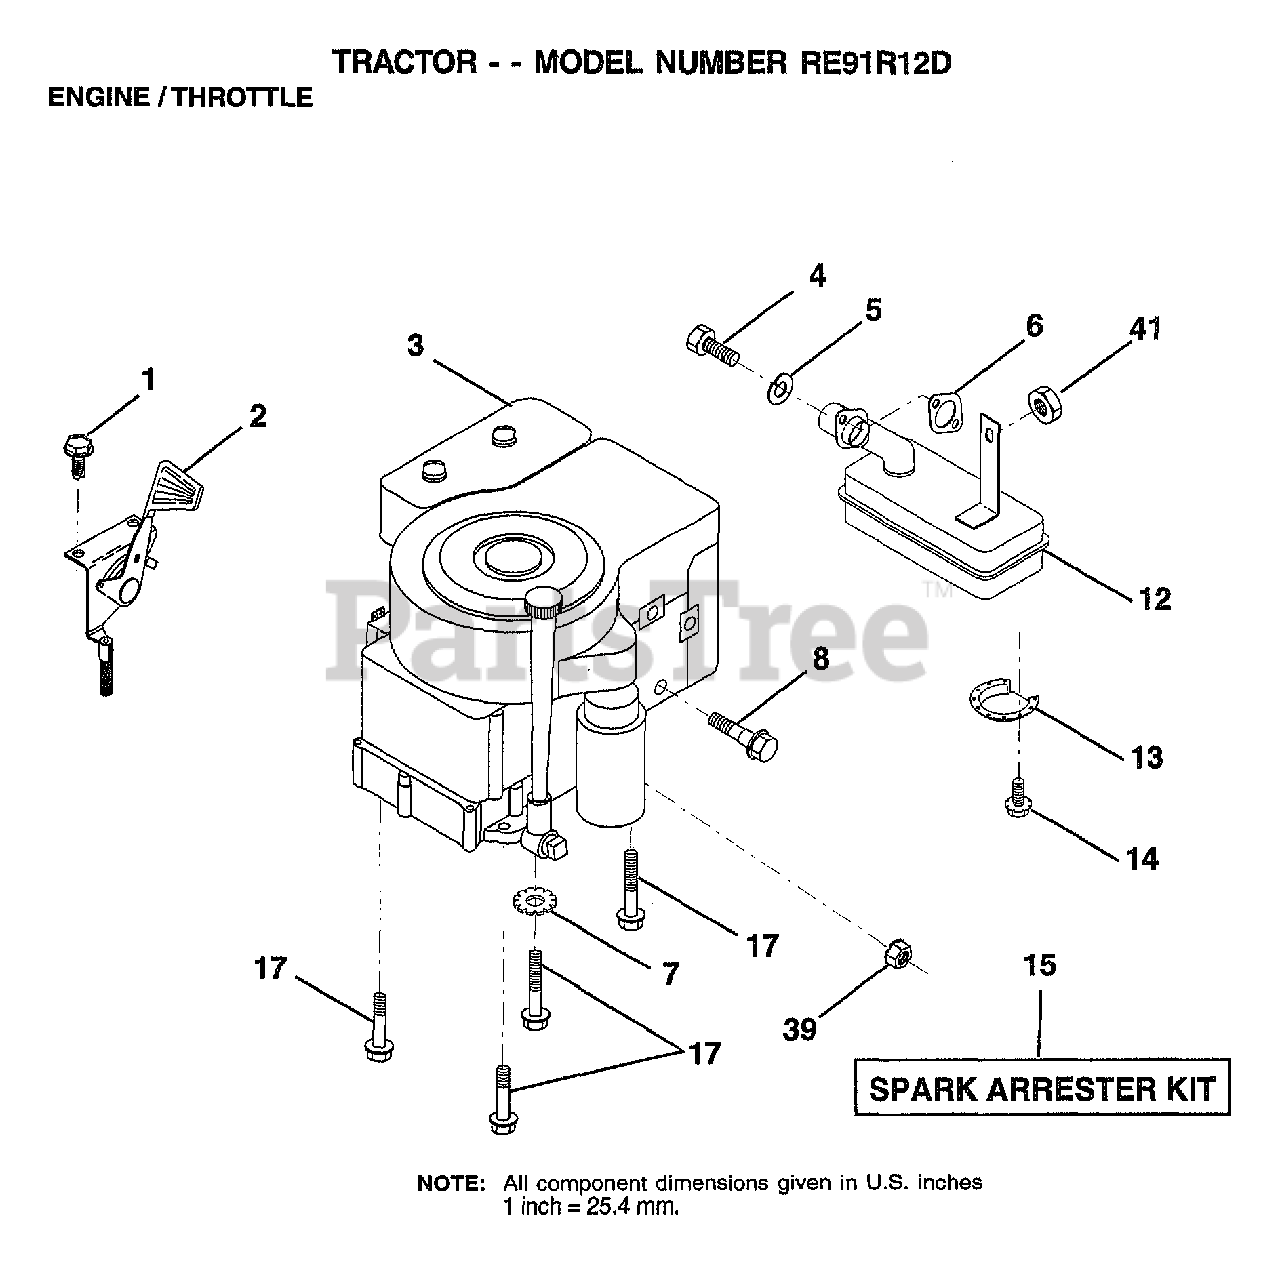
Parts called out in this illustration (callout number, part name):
1	SCREW LT
2	"CONTROL,THROTTLE"
4	SCREW HEX HD CAP
5	LOCKWASHER
7	LOCKWASHER
8	SHOULDER BOLT ST
12	MUFFLER-TECH 13HP
13	DEFLECTOR.222573
17	SCREW LT
39	NUT
41	"NUT HEX,LOCK,FLAN"
